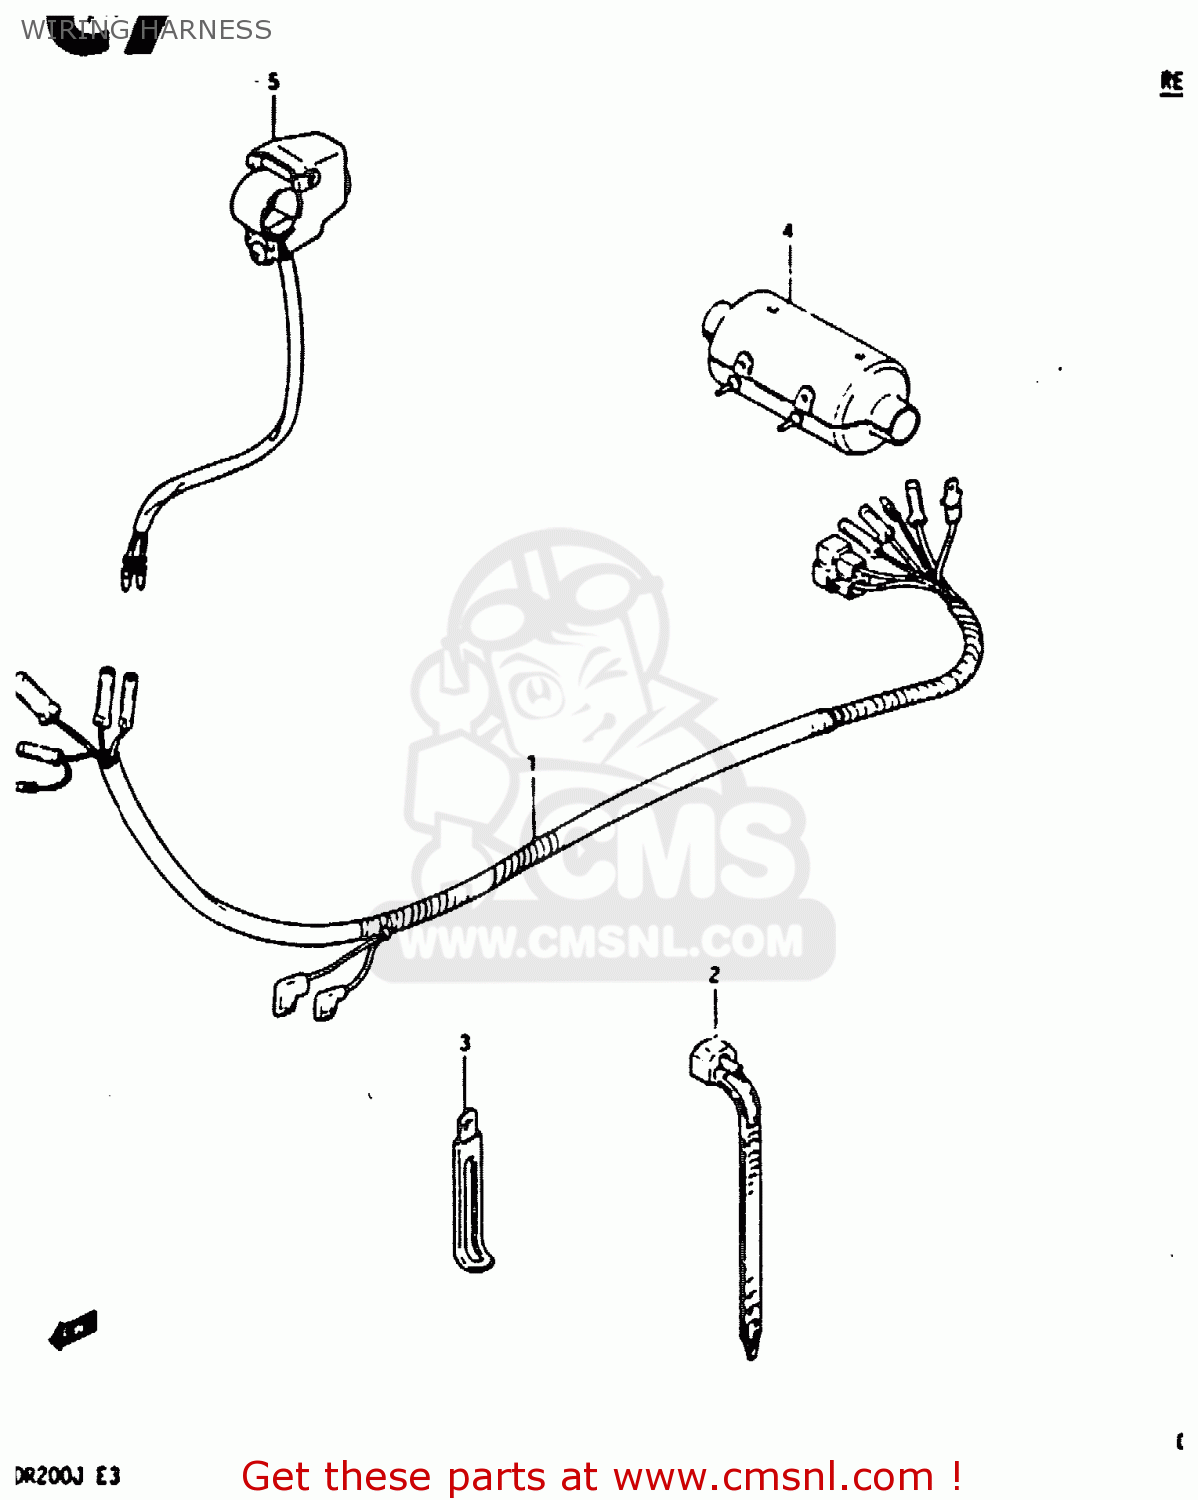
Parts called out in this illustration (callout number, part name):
1	HARNESS,WIRING
2	CLAMP(L:125)
3	CLAMP
4	BOOT,WIRING HARNESS
5	SWITCH ASSY,ENGINE STOP
